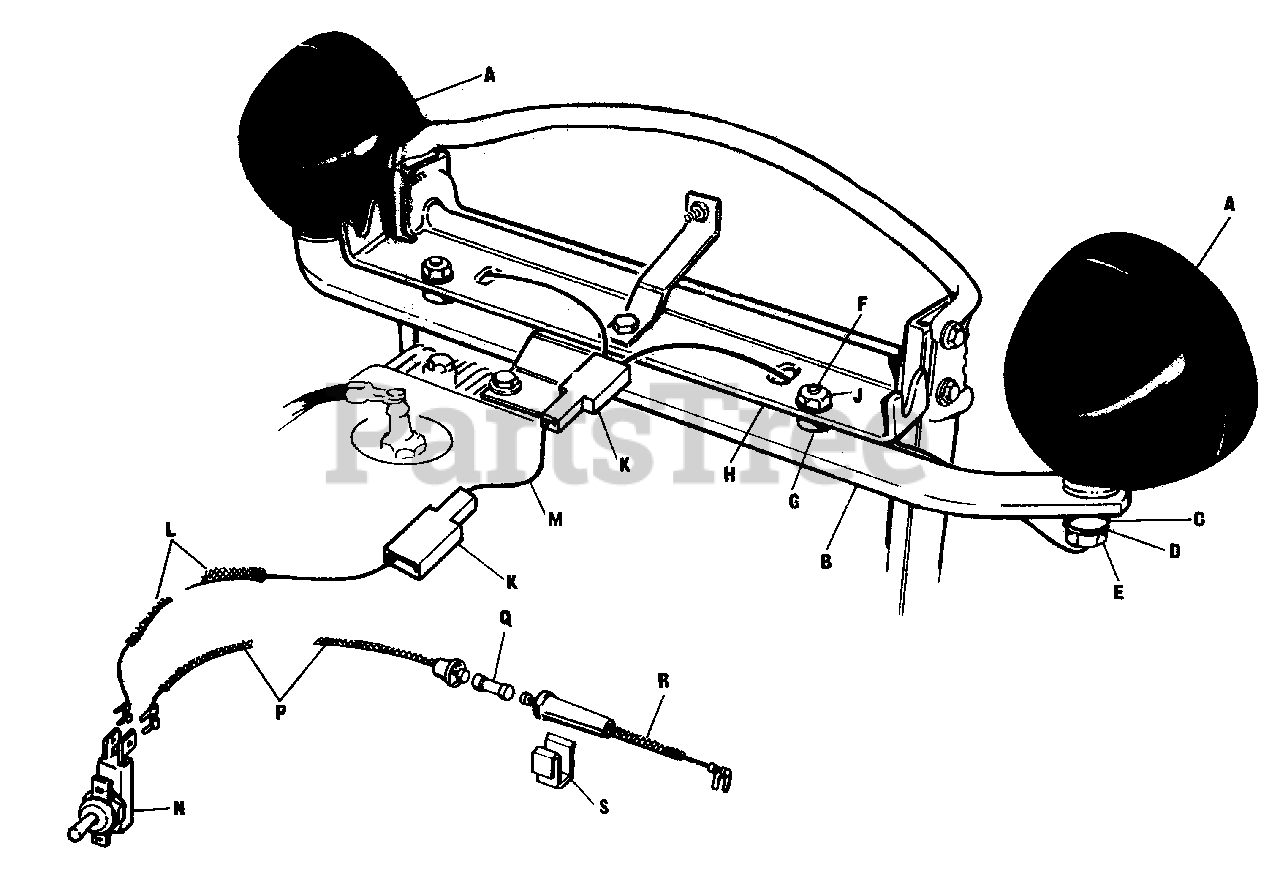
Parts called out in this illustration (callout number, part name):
A	Lamp Assembly
B	Light Support
D	Lock Washer, 1/2"
E	Full Hex. Nut, 1/2"-13
F	Hex. Cap Screw, 5/16"-18 x 1-1/2"
H	Lock Washer, 5/16"
J	Full Hex. Nut, 5/16"-18
K	Insulated Connector
L	Wire (switch to connector)
M	Extension Wire
N	Toggle Switch (with hardware)
P	Wire (fuse to switch)
Q	Fuse 20 Amp.
R	Wire (fuse to voltage reg.)
